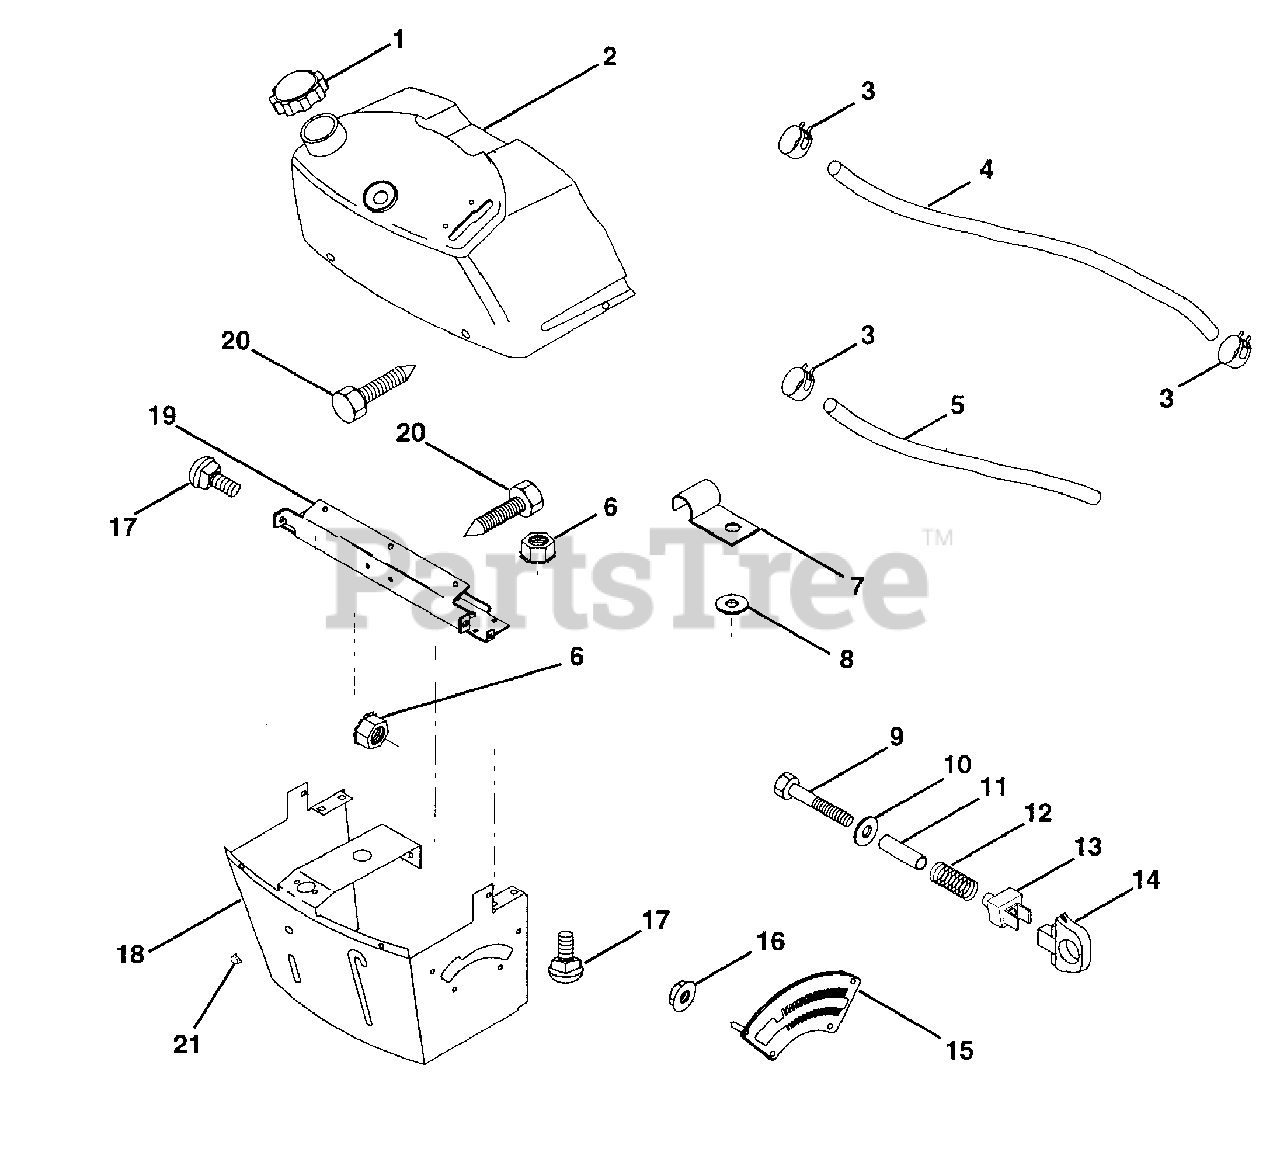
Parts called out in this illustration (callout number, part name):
1	Cap, Fuel
2	Assembly, Dash & Fuel Tank
3	Clamp, Hose
4	Line, Fuel
5	Line, Fuel
6	Nut, Hex, Keps 1/4-20
7	Clip, Fuel Line
8	Washer 9/32 x 3/4 x 16 Ga.
9	Bolt, Hex, Fin 1/4-20 x 1-3/4
10	Washer 11/32 x 11/16 x 16 Ga.
11	Spacer, Split
13	Clip, Height Adjustment
14	Knob, Height Stop
15	Adjustment, Quadrant Height
16	Nut, Self-Threading 3/16-18
17	Bolt, Carriage 1/4-20 x 1/2 Gr. 5
18	Support Assembly, Dash
19	Brace, Cross
20	Screw, Self-Tapping 1/4-20 x 1/2
21	Plug Dome Black
